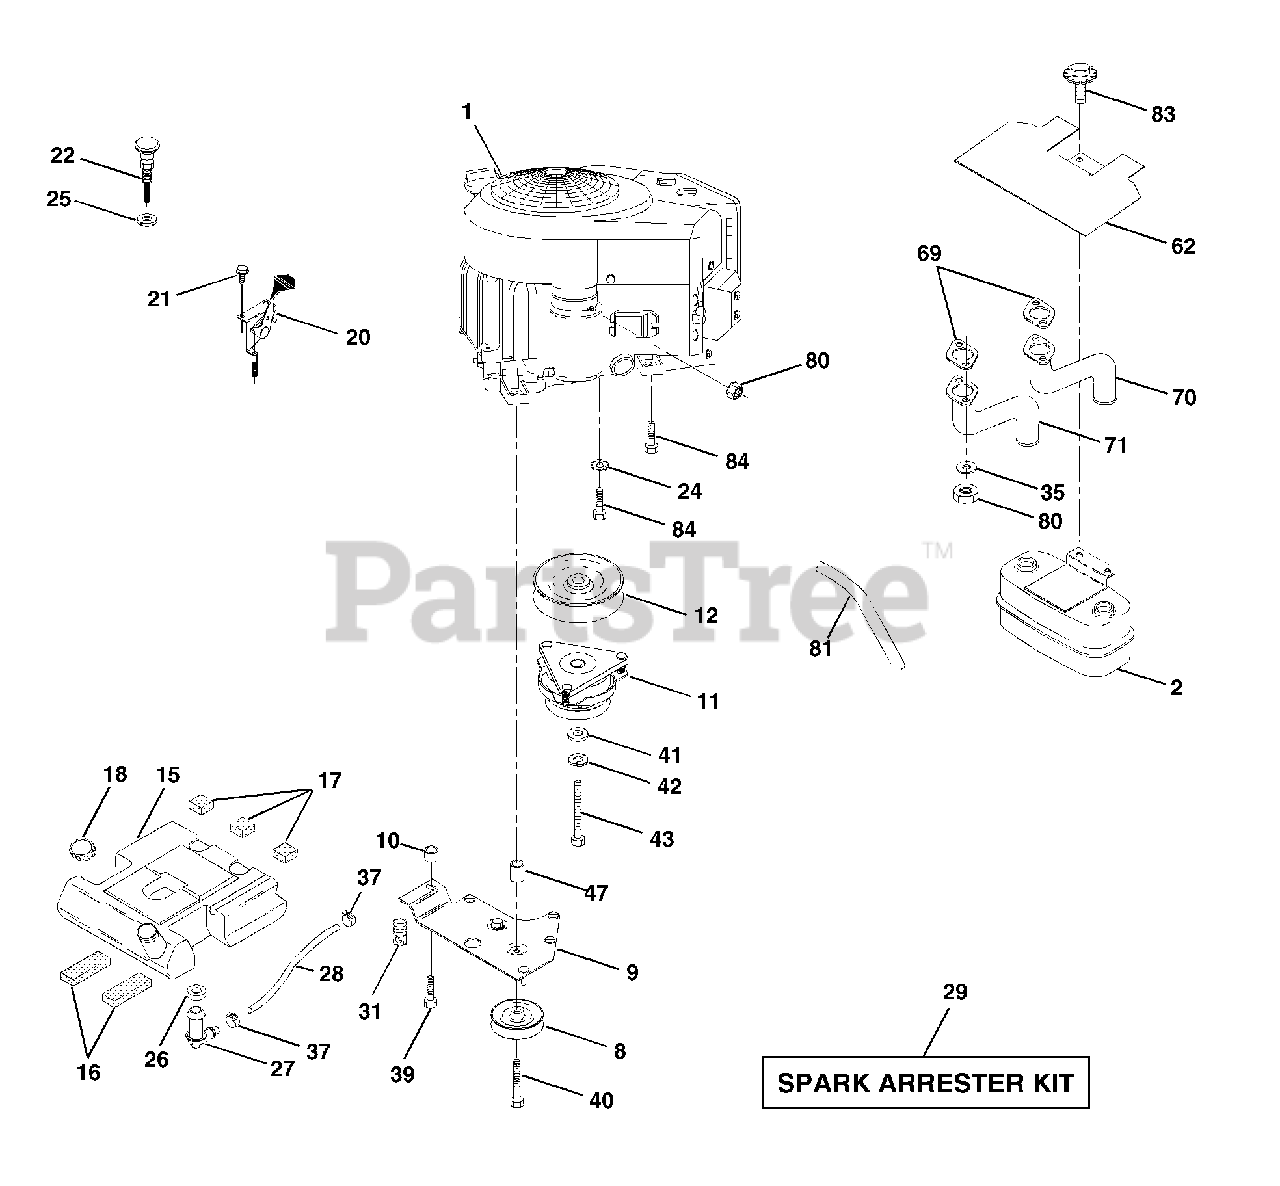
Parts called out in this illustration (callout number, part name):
2	Muffler Side
8	Pulley V-Idler
9	Keeper Asm. Belt Engine VGT
11	Clutch Electric
12	Pulley Engine VGT Elect Clutch
16	Pad Spacer
17	Pad Spacer
18	Cap Fuel
20	Control Throttle
21	Screw Hex Thd Cut 1/4 - 20 X 5/8
22	Control Choke
24	Washer Ext Tooth 3/8
25	Nut Keps 3/8-24 Unf
26	Bushing
27	Stem Tank Fuel
28	Fuel Line
29	Spark Arrester Kit
31	Clip Push-In Hinged
37	Clamp Hose
39	Screw TT 3/8-16 x 2-1/4 UNC
40	Screw TT 3/8-16 x 4 UNC
41	Washer 1-1/2 OD X 15/32 ID X .250
42	Washer Lock 7/16
43	Bolt Hex 7/16-20 X 3.75 Gr. 5
62	Shield Heat Muffler
69	Gasket
70	Tube Exhaust LH
71	Tube Exhaust RH
80	Nut Flange M8-1.25
81	Tube Drain Oil Easy
83	Bolt 5/16-18unc X 1-3/4 W/Sems
84	Screw 3/8-16 x 1-1/2
